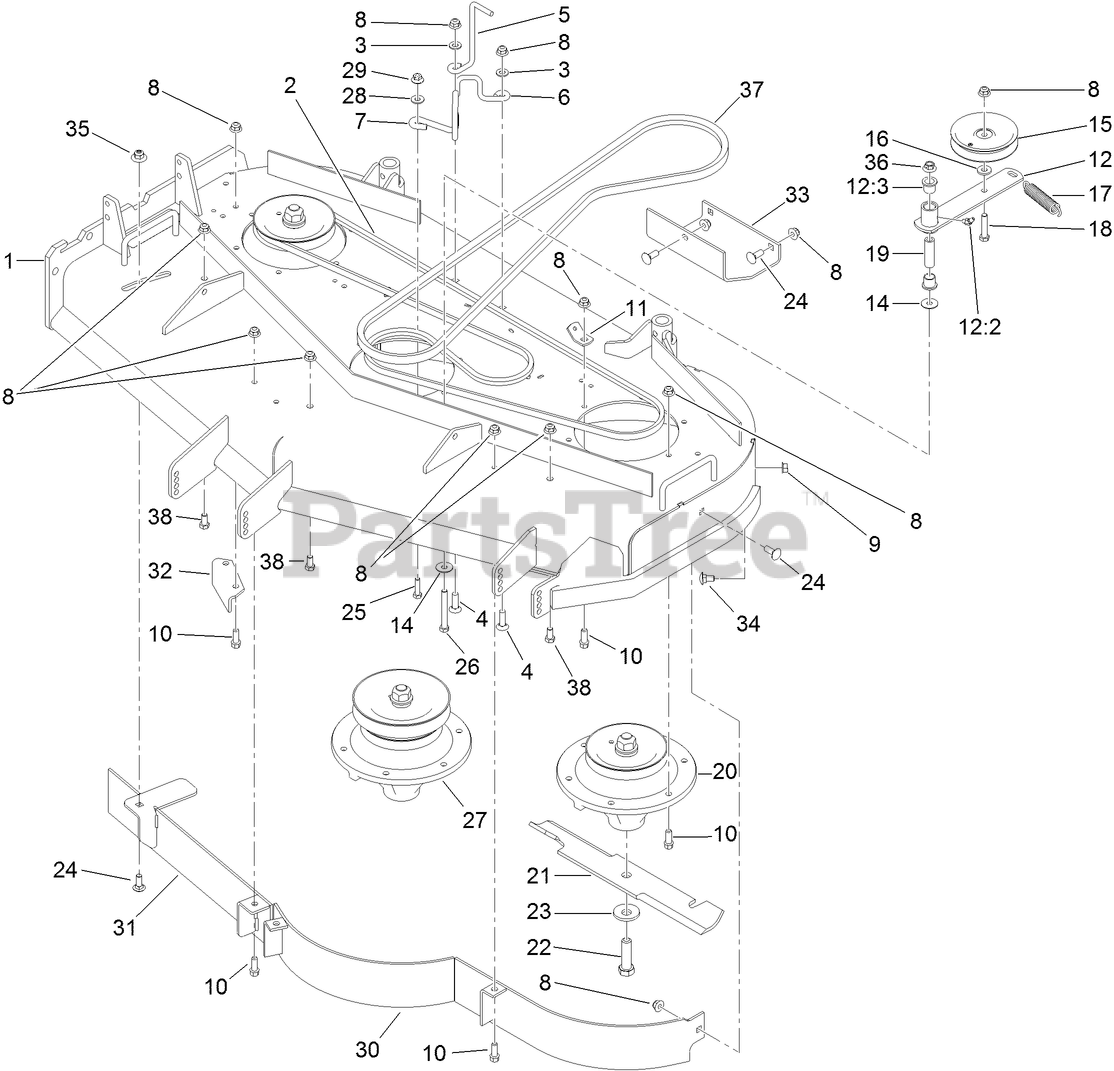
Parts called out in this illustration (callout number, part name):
1	DECK ASM
2	BELT-V
3	WASHER-FLAT
4	SCREW-CARR
5	GUIDE-BELT
6	GUIDE-BELT
7	GUIDE-BELT
8	NUT-HF, NI
9	NUT-HF
10	SCREW-HWH
11	PLATE-SPRING
12	IDLER ARM ASM
12:2	FITTING-LUBE, 45 DEG
12:3	BUSHING-FLANGE
14	WASHER
15	PULLEY-IDLER
16	WASHER-SPACER
17	SPRING-EXTENSION
18	SCREW-HH
19	SPACER
20	SPINDLE ASM
21	BLADE-16.5 INCH (HIGH FLOW)
22	SCREW-BLADE
23	Washer-Blade Bolt, Heavy
24	BOLT-CARR
25	SCREW-HH
26	SCREW-HH
27	SPINDLE ASM
28	WASHER-FLAT
29	NUT-HF
32	BAFFLE-DISCHARGE
34	SCREW-CARR
35	NUT-FLANGE, NI
36	NUT-HF
37	BELT-V
38	SCREW-HH
